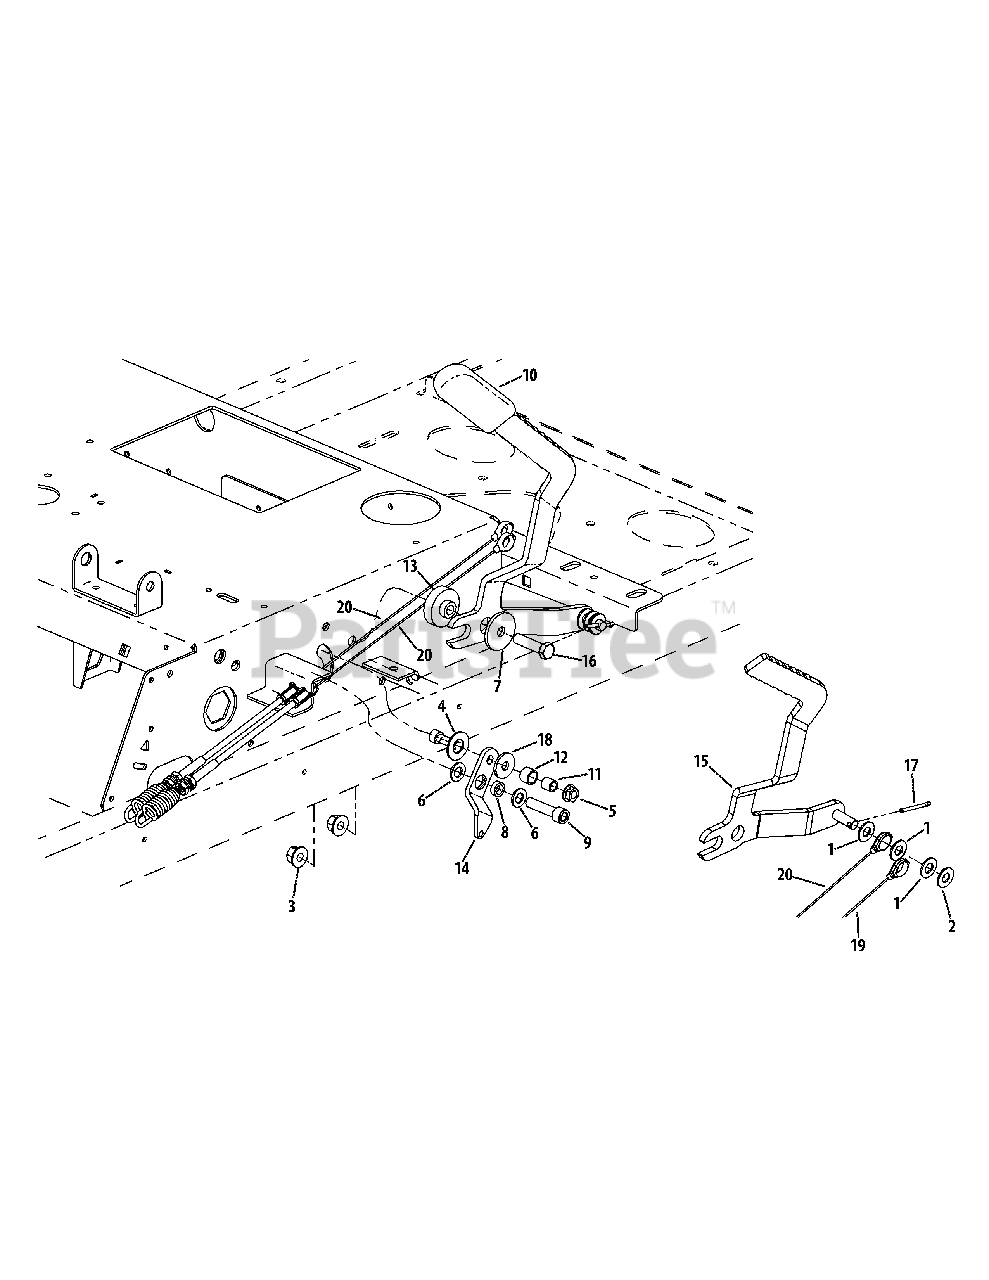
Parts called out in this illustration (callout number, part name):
1	Flat Washer, .406 x .812 x .062
2	Flat Washer, 3.8
3	Hex Nut, 3.8-16 Flange Lock
4	Slide Washer
5	Flange Lock Nut, 5.16-18
6	Washer, .375 x .738 x .063
7	Flat Washer, .390 x 1.5 x .134
8	Spacer, .380 x .563 x .196
9	Sockethead Capscrew, 3.8-16 x 1.50
10	Parking Brake Grip
11	Spacer, .322 x .438 x .44
12	Spacer, .442 x .563 x .405
13	Step Hub, .379 x 1.5 x .257/.400
14	Lockout Lever Plate
15	Brake Handle
16	Hex Head Cap Screw, 3.8-16 x 1.50
17	Cotter Pin, 1.8 x .75
18	Washer, .345 x 1.00 x .100
19	Left Hand Brake Cable
20	Right Hand Brake Cable
